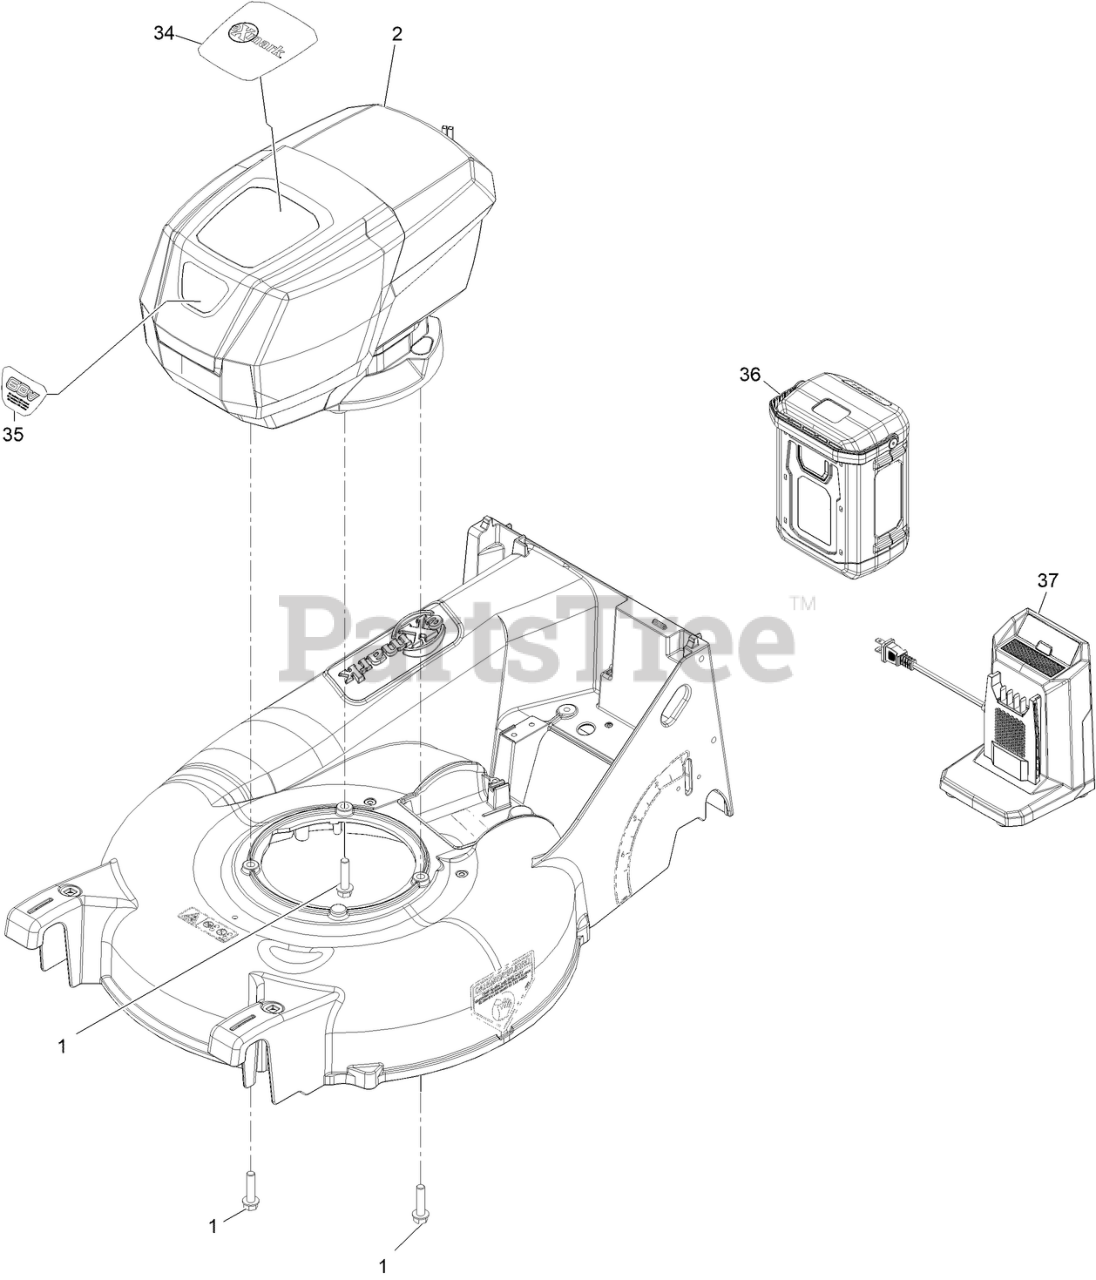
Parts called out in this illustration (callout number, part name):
1	SCREW-HWH
2	MOTOR MODULE
34	DECAL-HOOD,TOP
35	DECAL-HOOD,FRONT
36	BATTERY-LI-ION, 60V 10 AH, 540WH
37	CHARGER-RAPID
